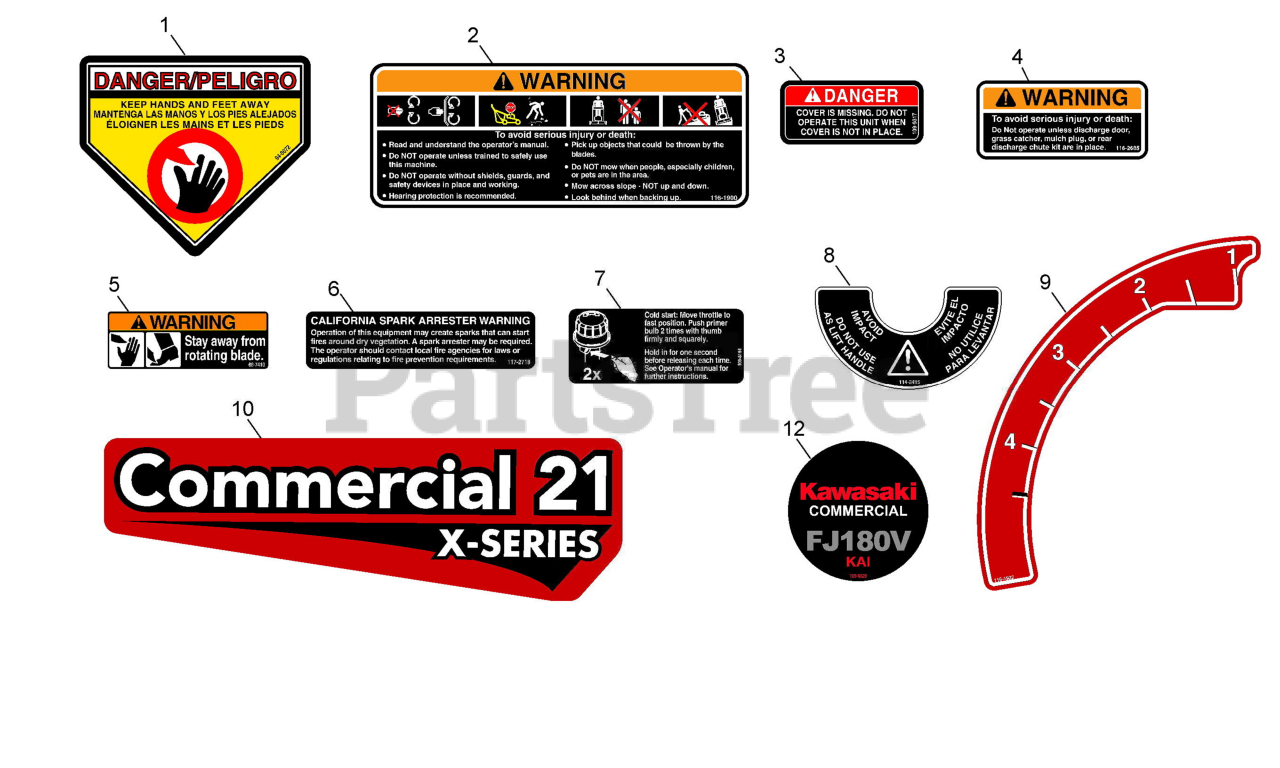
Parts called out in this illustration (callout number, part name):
1	DECAL-DANGER
2	DECAL-WARNING
3	DECAL-COVER MISSING
4	DECAL-WARNING DOOR SM
5	DECAL-BLADE
6	DECAL-ARRESTER, SPARK
7	DECAL, PRIMER
9	DECAL-HEIGHT OF CUT
10	DECAL-COMM 21 X-SERIES
